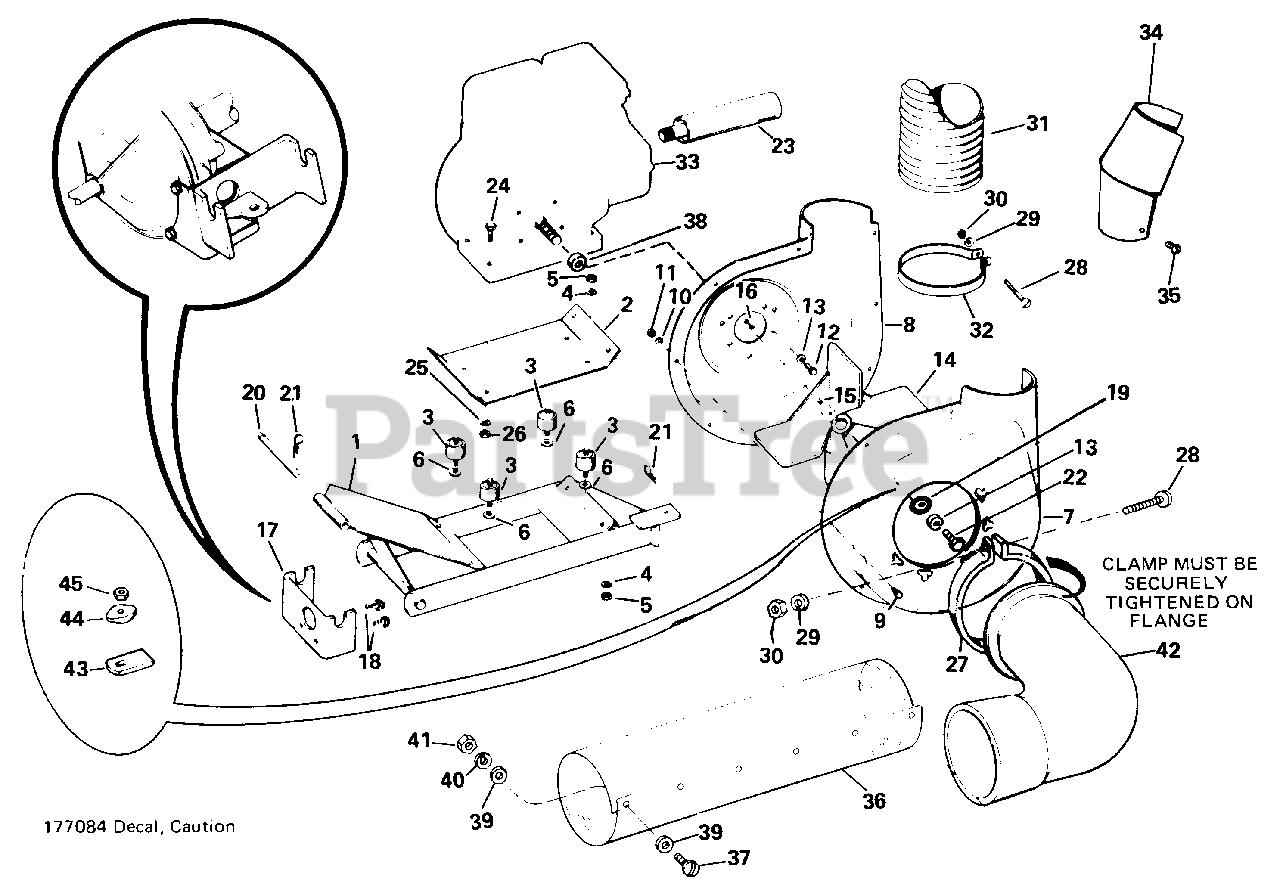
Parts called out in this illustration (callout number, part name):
1	FRAME ASSEMBLY
2	PLATE, Engine
3	CUSHION, Connector
4	LOCKWASHER, 5/16
5	NUT, full hex, 5/16
6	WASHER, Plain, 5/16
7	HOUSING ASSEMBLY
8	HOUSING, Half blower, R.H.
9	CAPSCREW, Hex, 1/4-20 x 1/2
10	LOCKWASHER, 1/4
11	NUT, full hex, 1/4-20
12	CAPSCREW, Hex, 5/16-24 x 5/8
13	LOCKWASHER, 5/16
14	FAN ASSEMBLY
15	SETSCREW, 5/16-18 x 1/2
16	KEY
18	CAPSCREW, Hex, 3/8-16 x 1-1/2
20	PIN, Counterweight
21	CLIP, Spring
22	CAPSCREW, Hex, 5/16-24 x 3/4
24	CAPSCREW, Hex, 5/16-18 x 1-1/2
25	LOCKWASHER, 5/16
26	NUT, full hex, 5/16-18
27	CLAMP, Hose
28	SCREW, Rd., Hd., Mach., 1/4-20 x 3
29	LOCKWASHER, 1/4
30	NUT, full hex, 1/4-20
31	HOSE, Exhaust
32	CLAMP, Hose
34	DEFLECTOR
35	SCREW, Self-tap., No. 10
36	TUBE, Intake
37	SCREW, Truss Head., Phillips No. 10
39	WASHER, 3/16
40	LOCKWASHER, No. 10
41	NUT, full Hex, No. 10-32
42	ELBOW ASSEMBLY, 42" Adapter
44	NUT, Wing
45	LOCKNUT, Full Hex, 5/16-18
